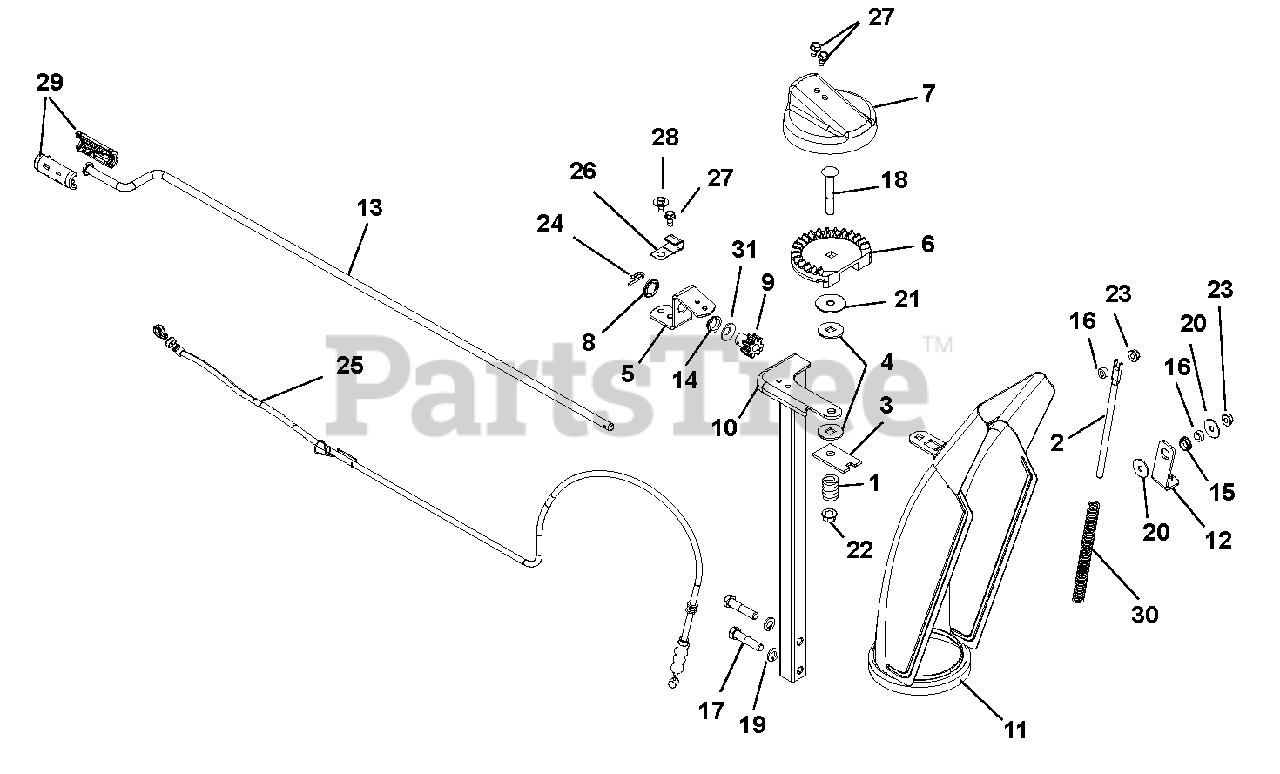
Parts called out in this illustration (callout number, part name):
1	SG-COMP .187X.56X1.62
2	ROD, DEFLECTOR CAP
3	PLATE, FRICTION
4	FRICTION WASHER
5	BRACKET, PINION GEAR
6	CHUTE GEAR
7	GEAR COVER
8	PUSHNUT .625
9	PINION GEAR W/BRACKET
10	CHUTE PEDESTAL, TALL COMPACT
11	CHUTE, DISCHARGE W/REM.CAP,DEC
12	BRACKET, CABLE ANCHOR
13	ROD, CHUTE CRANK, COMP&SNOTEK
14	BUSHING, POLYLINER-.63 SNAPIN
15	BUSHING, POLYLINER-.50 SNAPIN
16	BSHG-SLV .265X.500X.219
17	@BLT-HEX .38-16X1.75 GR5 YWZC
18	@BLT-RDHDSQNK .38-16X2.50 G5YZ
19	@WSHR-LK .38X.094 REG YWZC
20	WSHR-FL-STL .281X1.000X.063
21	@WSHR-FL-STL .406X1.25X.10 ZC
22	@NUT-LK-TOP-FLG .38-16 YWZC
23	@NUT-LK-TOP-FLG .25-20 YWZC
24	PIN, SPRING CLIP
25	CABLE, DEFLECTOR - COMPACT
26	J-CLAMP
27	SCR-TAP .25-20X.50 HWH TR YWZ
28	SCR-TAP .25-20X.50 LGHWH TR YZ
29	KNOB, CHUTE CRANK - SNAP BLK
30	SG-COMP .08X.40X6.50 14#/IN
31	WSHR-THRST .625 X 1.0 X .03
